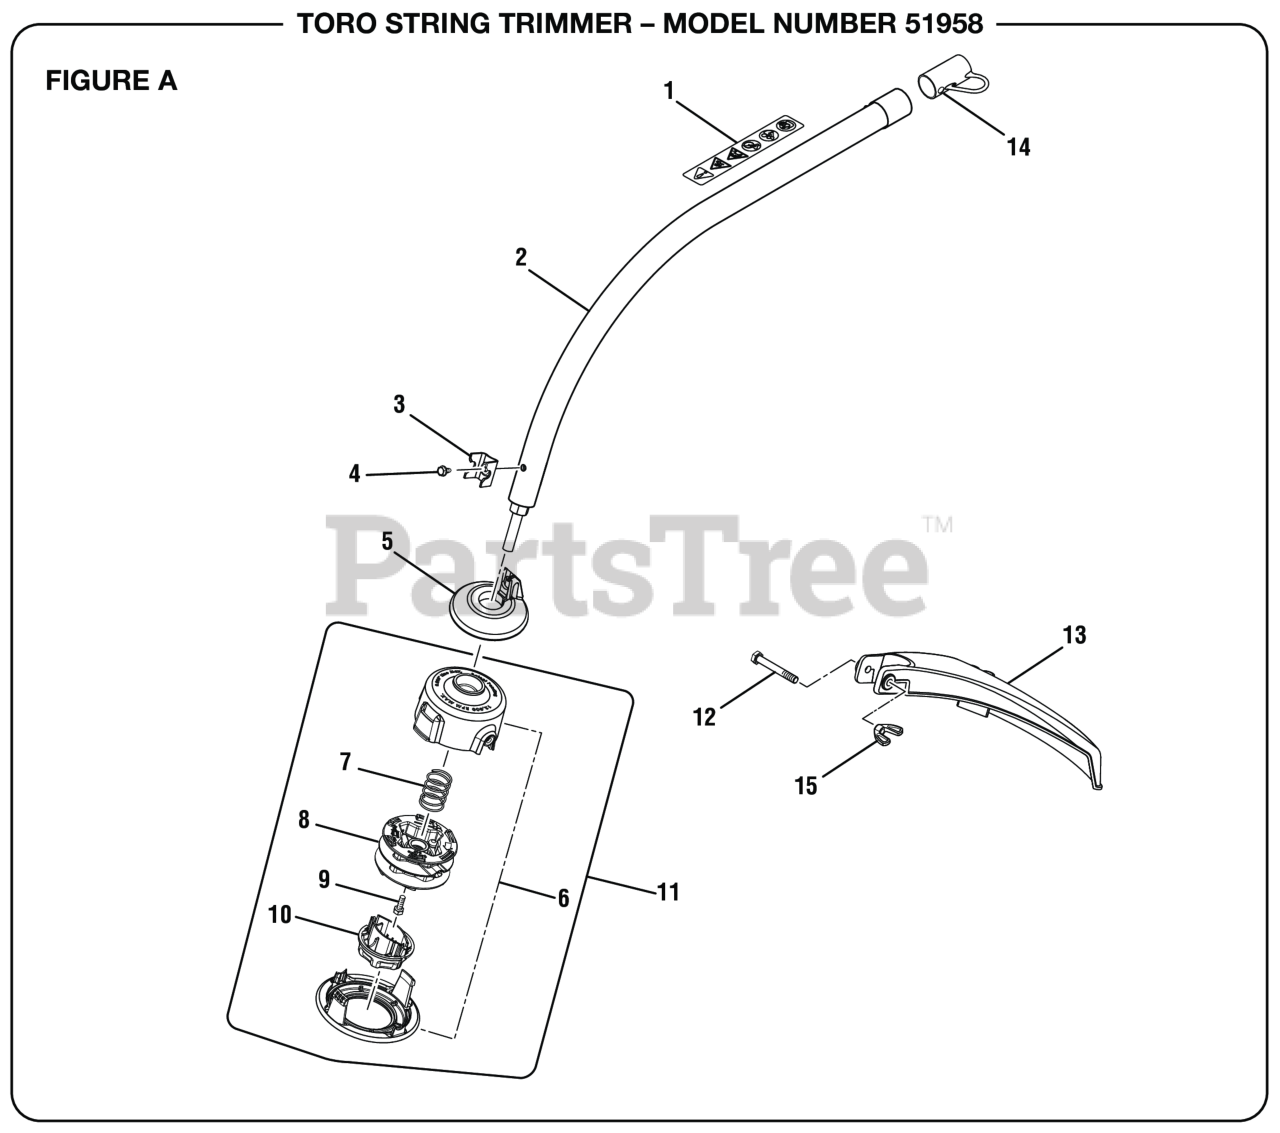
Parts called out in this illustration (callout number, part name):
1	Warning Icon Label
2	Curved Shaft Assembly
4	Screw (#10-32 x 3/8 in., Hex Washer Hd. S.T.)
5	Curved Shaft Grass Deflector
6	Stringhead Housing
7	Compression Spring
8	Spool Assembly
9	Bolt (5/16-18 x 1/2 in.)
10	Bump Knob
11	Trimmer Head Assembly (.095)
12	Bolt (5/16-18 x 1/2 in.)
13	Grass Deflector Assembly
14	Hanger Cap
15	Wing Nut (1/4-20, Plastic)
